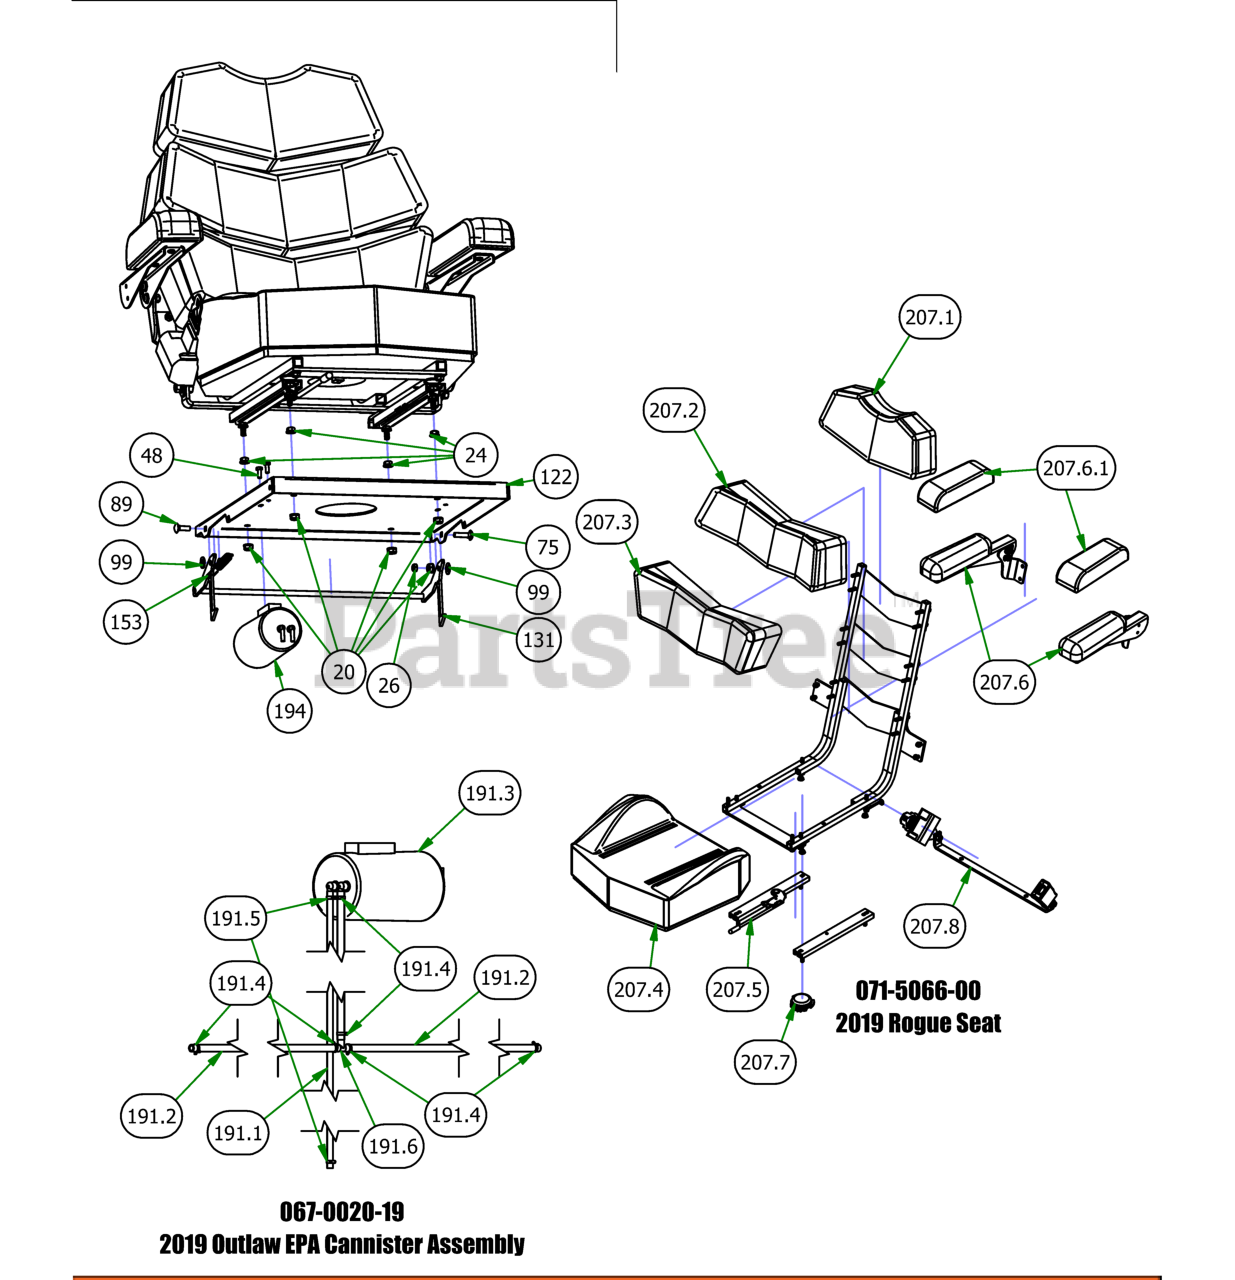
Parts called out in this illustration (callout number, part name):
191.1	3/16" Vinyl Tubing, 66" Long
191.2	1/4" Vinyl Tubing 38" Long
191.3	Carbon Canister
191.4	3/16 Vinyl Clamp
191.5	3/16" Vinyl Hose Clamp
191.6	fuel line T
207.1	Back Pad # 1 for 071-5066-00
207.2	Back Pad # 2 for 071-5066-00
207.3	Back Pad # 3 for 071-5066-00
207.4	Seat Pad Assembly for 071-5066-00
207.5	Seat Rails for Outlaw Seat/2020 ZT Elite/ZTAvenger
207.6	Arm Rest Kit for 071-5066-00
207.6.1	Pair of Arm Pads for the
207.7	2014 Magnum Seat Switch
207.8	Seat Belt for 071-5066-00
